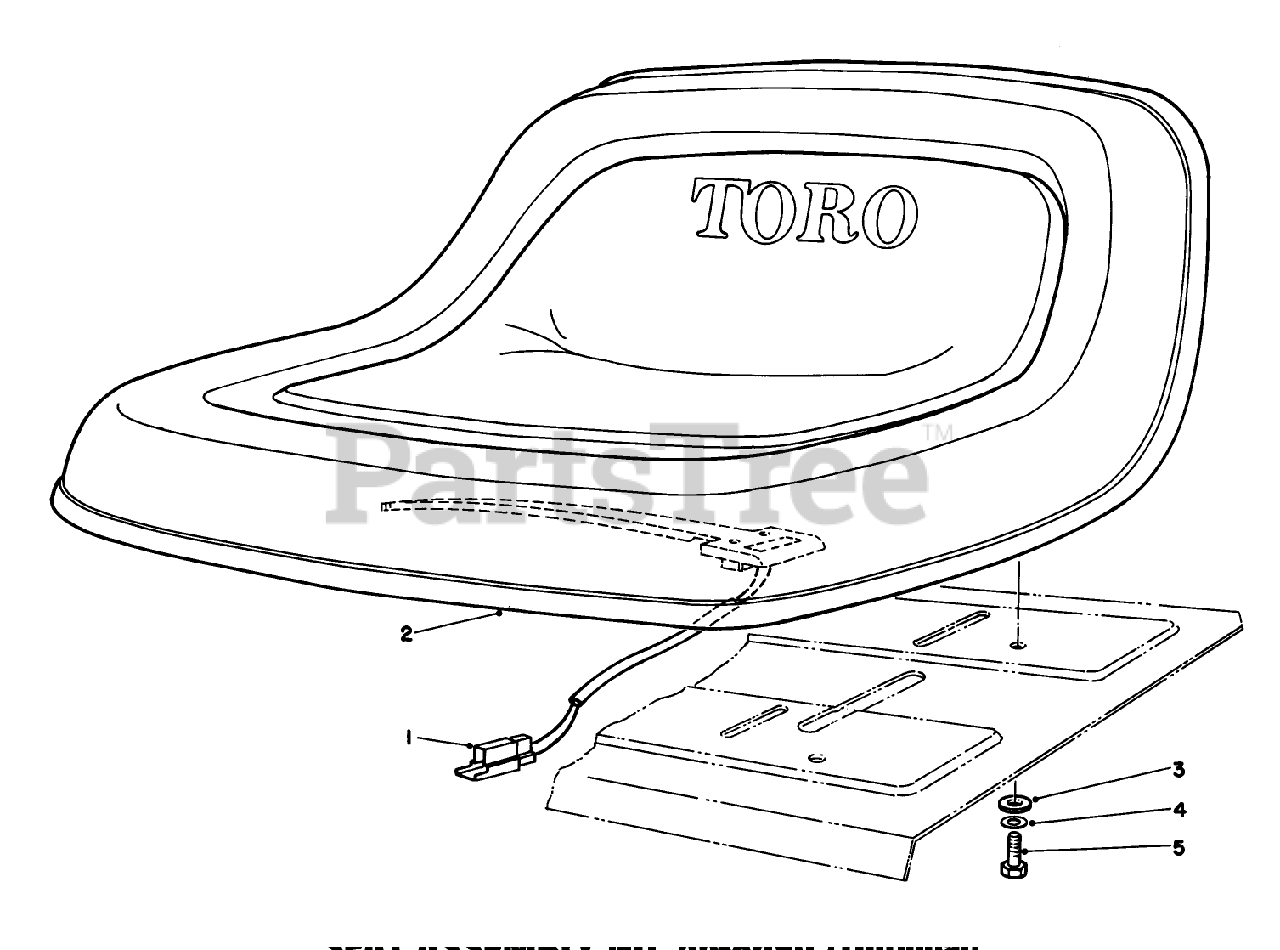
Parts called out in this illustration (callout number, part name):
1	SWITCH-SEAT
2	Seat
3	WASHER-PLAIN
4	WASHER-LOCK
5	SCREW-HH
